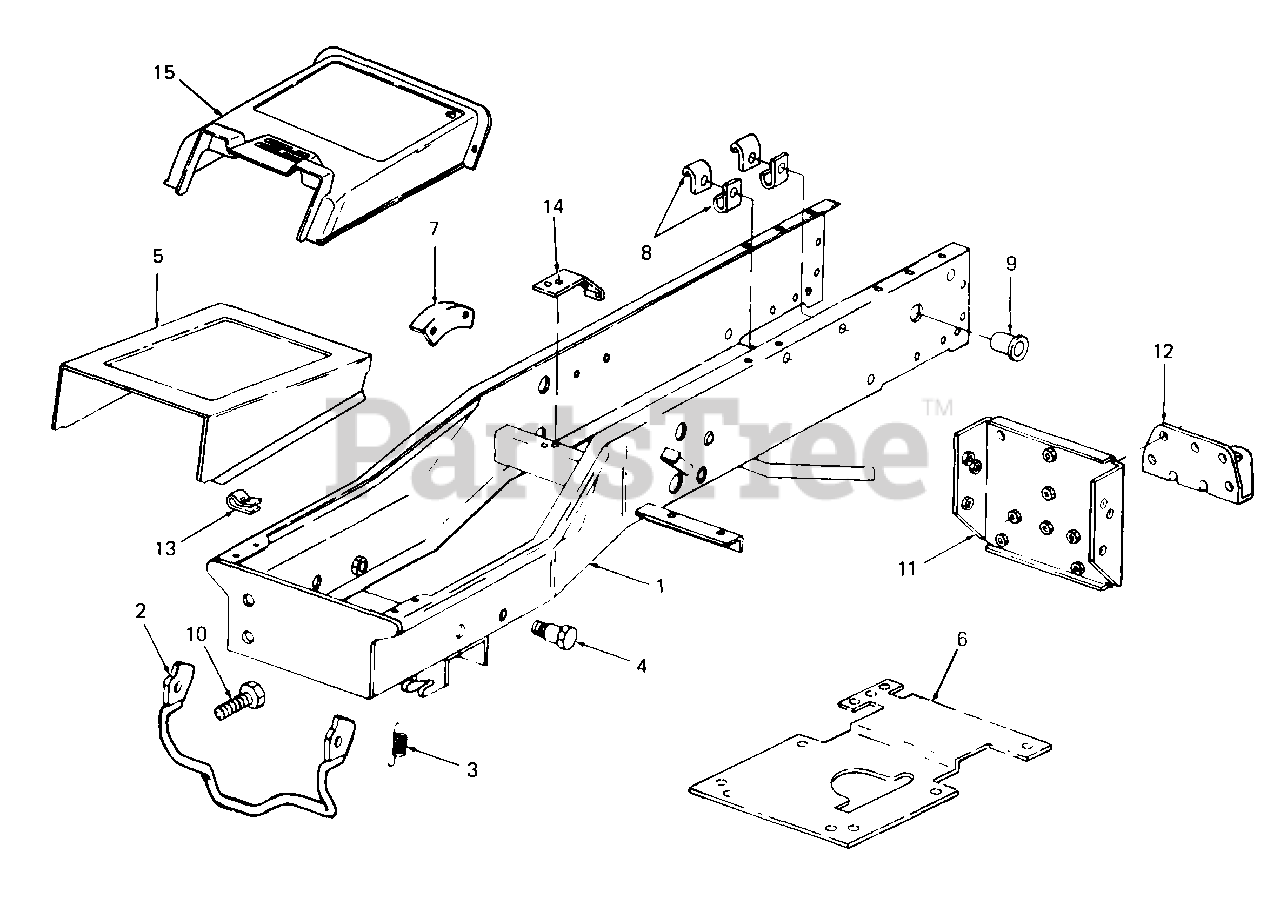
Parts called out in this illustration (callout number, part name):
3	Spring, Latch
4	Bolt, Shoulder
5	Cover, Frame w/Graphic
7	Bracket, Height Indicator
8	Clip, Cable
9	Bushing, Snap
10	Screw, Adjustment, 1/2-20 x 1.0 Lg GR5
13	Nut, Speed
14	Bracket, Switch
15	Cover, Frame
